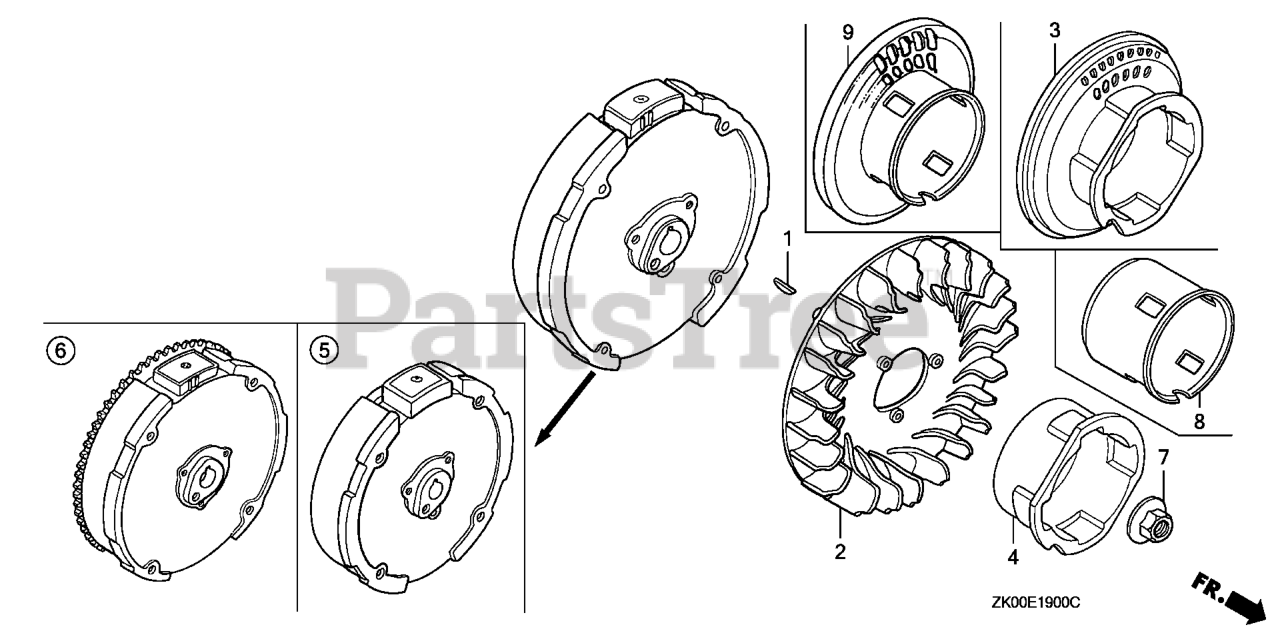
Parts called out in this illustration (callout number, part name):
1	KEY, SPECIAL WOODRUFF (25X18)
2	FAN, COOLING
4	PULLEY, STARTER
5	FLYWHEEL (LAMP)
7	NUT, SPECIAL (14MM)
8	PULLEY, STARTER
